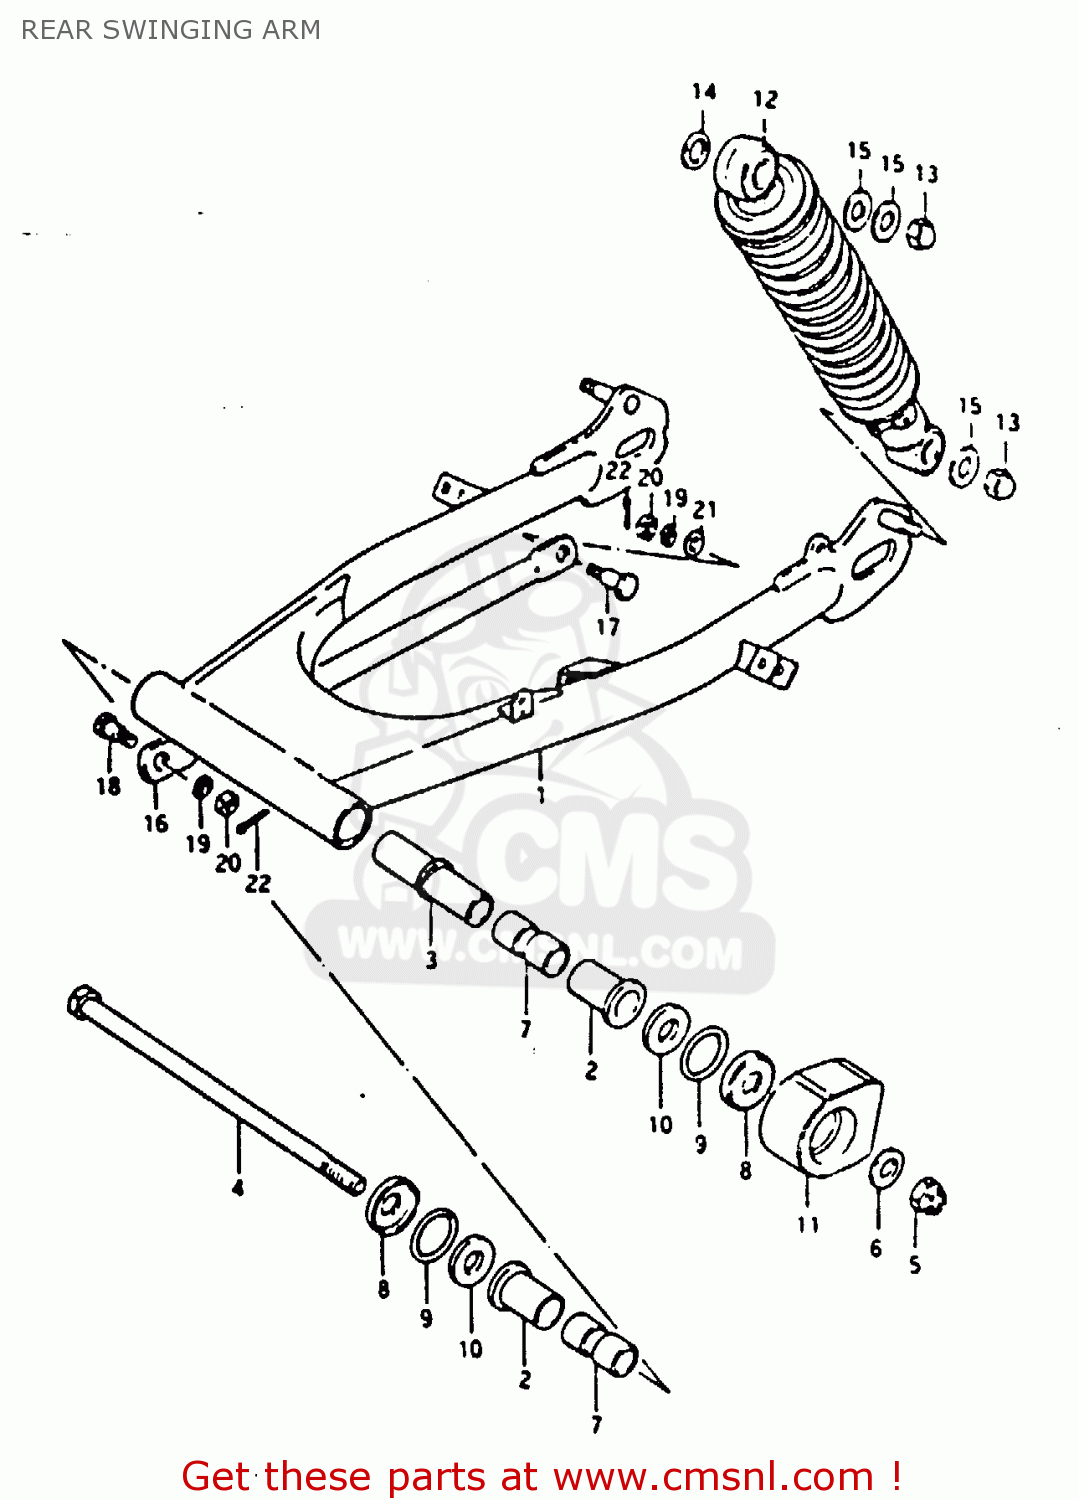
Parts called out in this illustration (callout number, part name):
1	REAR SWINGING ARM SET
2	BUSH
3	SPACER,RR SWGARM PIVOT CTR
4	SHAFT,REAR SWING ARM
5	NUT
6	WASHER
7	SPACER,RR SWGARM PIVOT
8	COVER,SWGARM BUSH DUST SEAL
9	O RING(D:2,ID:24.5)
10	WASHER(12.5X24X2.3)
11	BUFFER,CHAIN TOUCH DEFENSE
12	13
13	NUT, LOWER LH
14	WASHER
15	WASHER
16	LINK,REAR TORQUE
17	BOLT(8X22)
18	BOLT(8X26.5)
19	LOCK WASHER
20	NUT
21	WASHER
22	PIN 20X20
